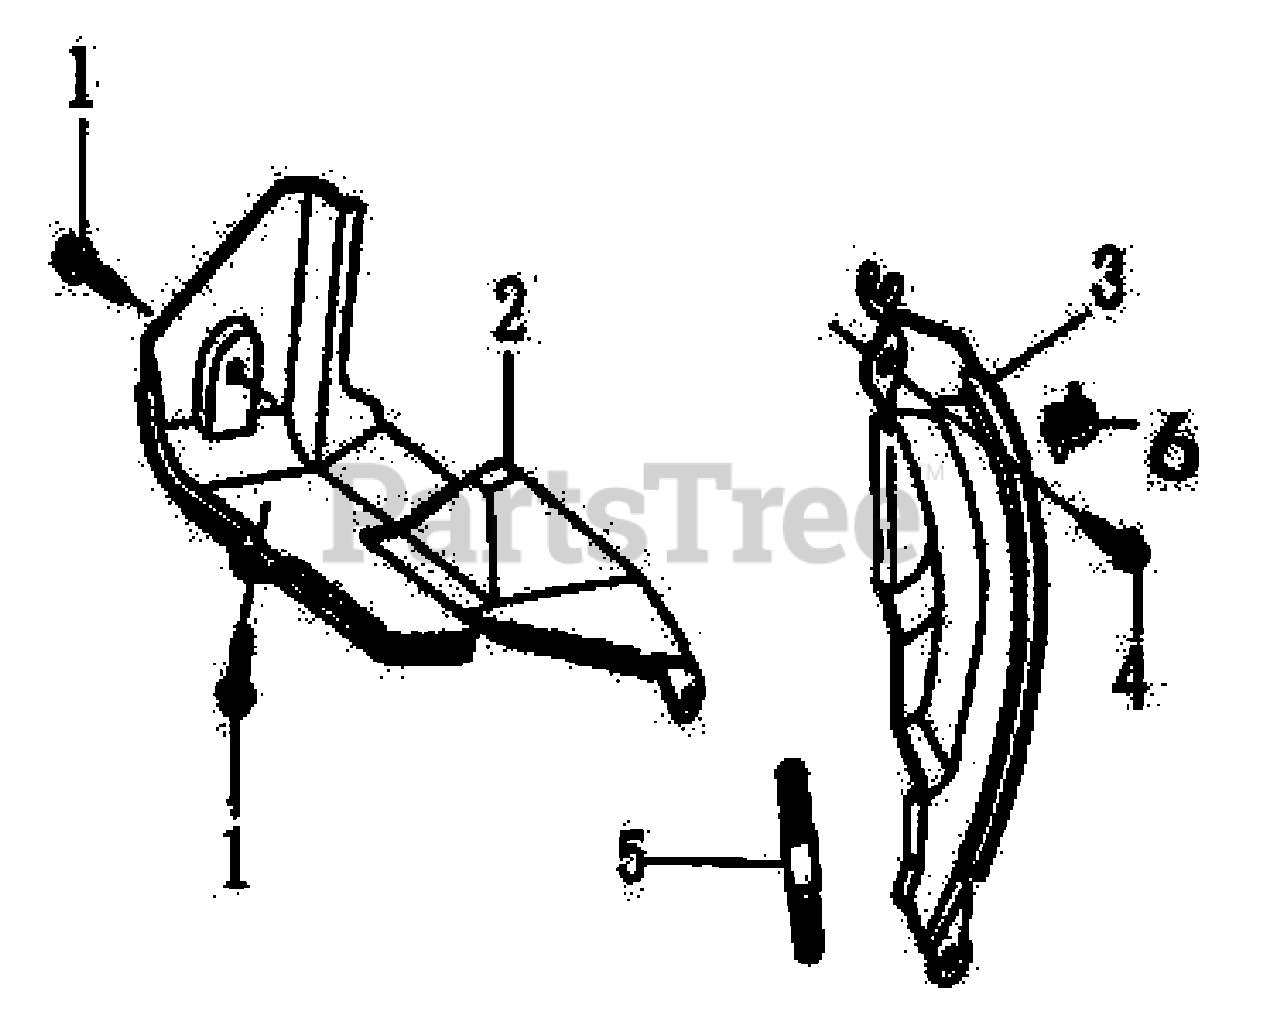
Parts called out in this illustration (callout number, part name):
1	BOLT, FLANGE 6X8
2	SHROUD COMPLETE
3	PLATE, SIDE
4	BOLT, FLANGE 6X20
5	BOLT, STUD
6	LOCATION CABLE CLIP
